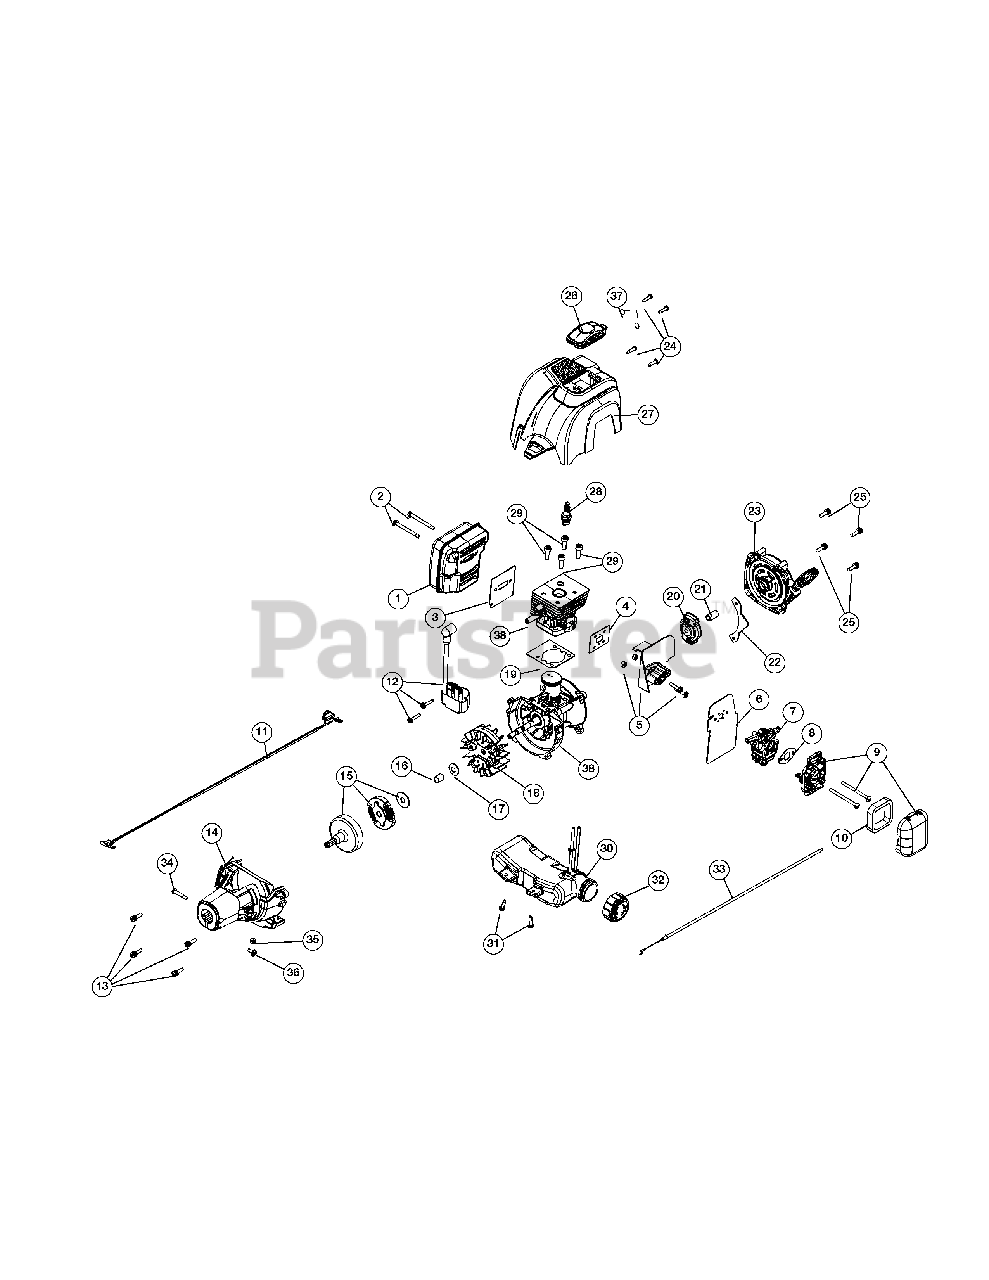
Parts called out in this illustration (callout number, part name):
1	Muffler Assembly (Incl. Ref 2 & 3)
2	Muffler Bolts
3	Muffler Gasket
5	Insulator Assembly (Incl. Ref 4)
6	Heat Shield
7	Carburetor
8	Carburetor Gasket
9	Aircleaner Assembly (Incl. Ref 10)
10	Aircleaner Filter
12	Module Assembly
13	Clutch Cover Screws
14	Clutch Cover Assembly (Incl. Ref 13)
15	Clutch Assembly
18	Flywheel Assembly
19	Cylinder Gasket
20	Pawl Assembly
21	Electric Starter Adapter
22	Starter Cover Guard (Incl. Ref 25)
23	Starter Assembly (Incl. Ref 22 & 25)
26	Spark Plug Cover
27	Engine Cover (Incl. Ref 24)
28	Spark Plug
29	Cylinder Screws
30	Fuel Tank Assembly (Incl. Ref 31 & 32)
31	Fuel Tank Screws
33	Throttle Cable
34	Screw
36	Anti-Rotation Screw
37	Wire Guard
38	Shortblock
